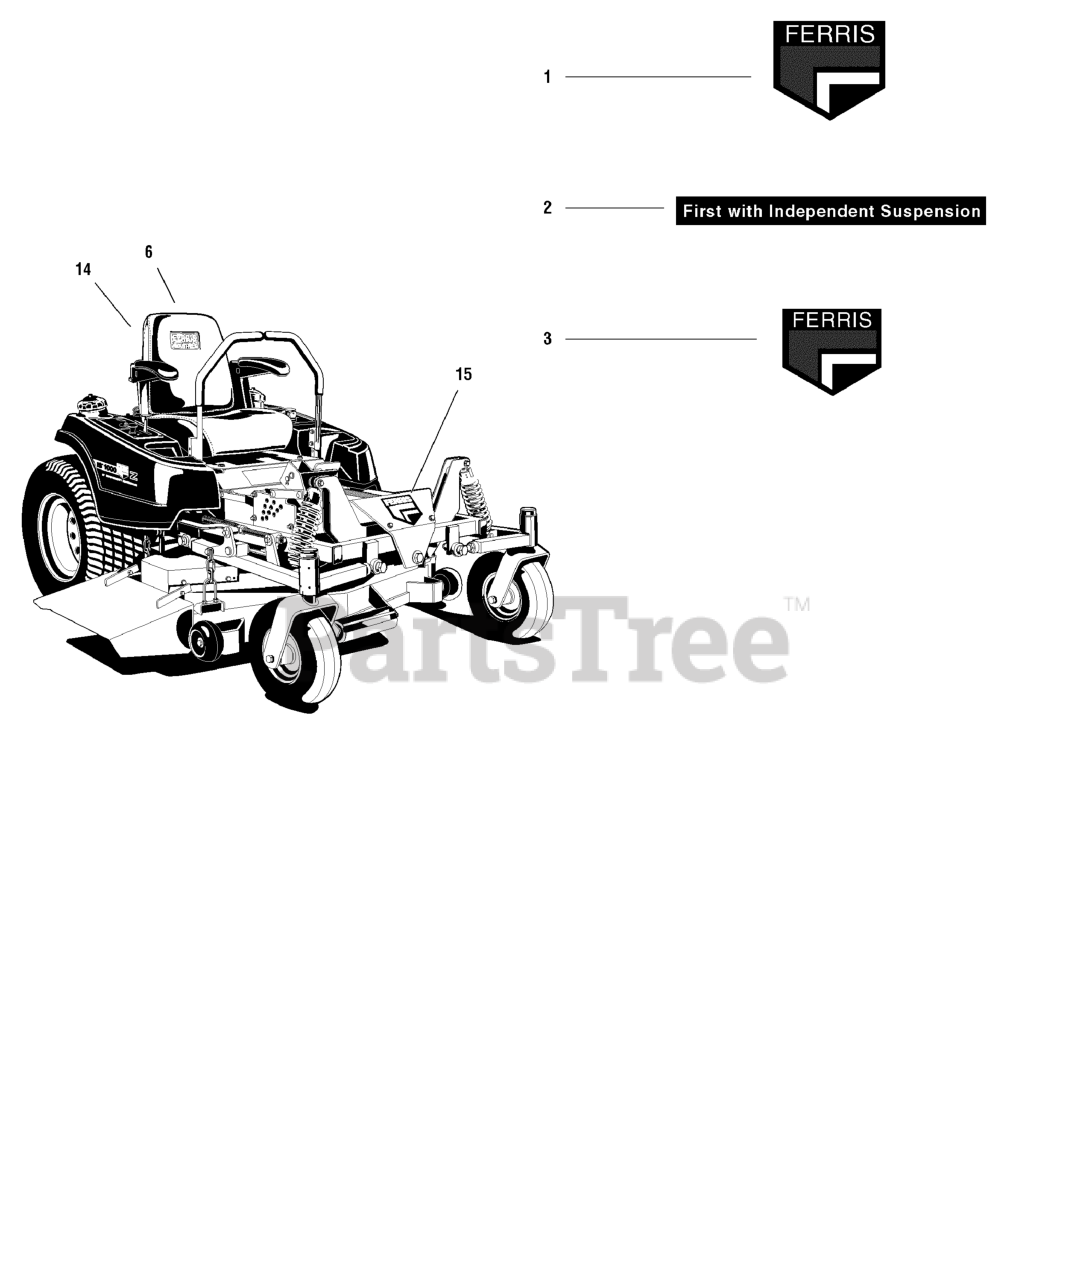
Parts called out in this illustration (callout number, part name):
1	DECAL, Ferris Logo, 6-3/8"
2	DECAL, First w/ Independent Suspension
3	DECAL, Ferris Logo, 5"
